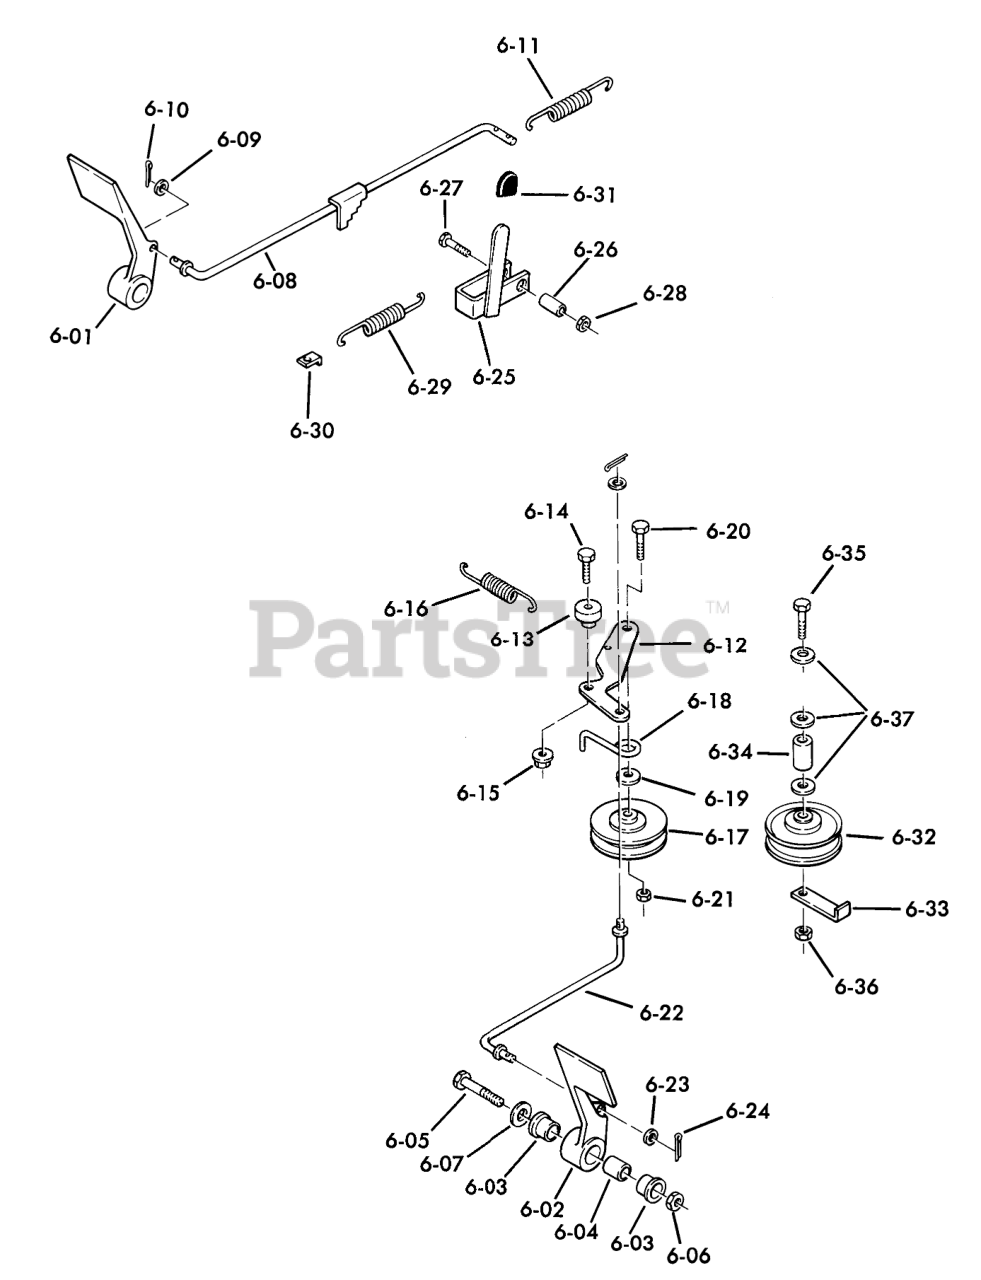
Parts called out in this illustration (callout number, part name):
6-01	PEDAL-BRAKE R
6-02	Clutch Pedal
6-03	BUSHING
6-04	Spacer
6-05	H H C S
6-06	Eslok Nut
6-07	Washer
6-08	Brake Rod
6-09	WASHER 5/16 NYLON
6-10	Pop Rivet
6-11	SPRING-EXTENSION
6-12	Clutch Lever
6-13	SPACER-CLUTCH LINK
6-14	BOLT
6-15	LOCKNUT-FLANGE
6-16	SPRING-EXTENSION
6-17	PULLEY-IDLER STATION
6-18	RETAINER-BELT
6-19	Washer
6-20	Bolt
6-21	Nut
6-22	Assy-Rod Clutch
6-23	WASHER-NYLON
6-24	Pop Rivet
6-25	Assy-Brake Lever
6-26	SPACER
6-27	Carriage Bolt
6-28	LOCKNUT-FLANGE
6-29	SPRING-EXTENSION
6-30	CLIP - SPRING
6-31	GRIP
6-32	Idler Pulley
6-33	Belt Retainer
6-34	Spacer
6-35	Bolt
6-36	Nut
6-37	Washer
